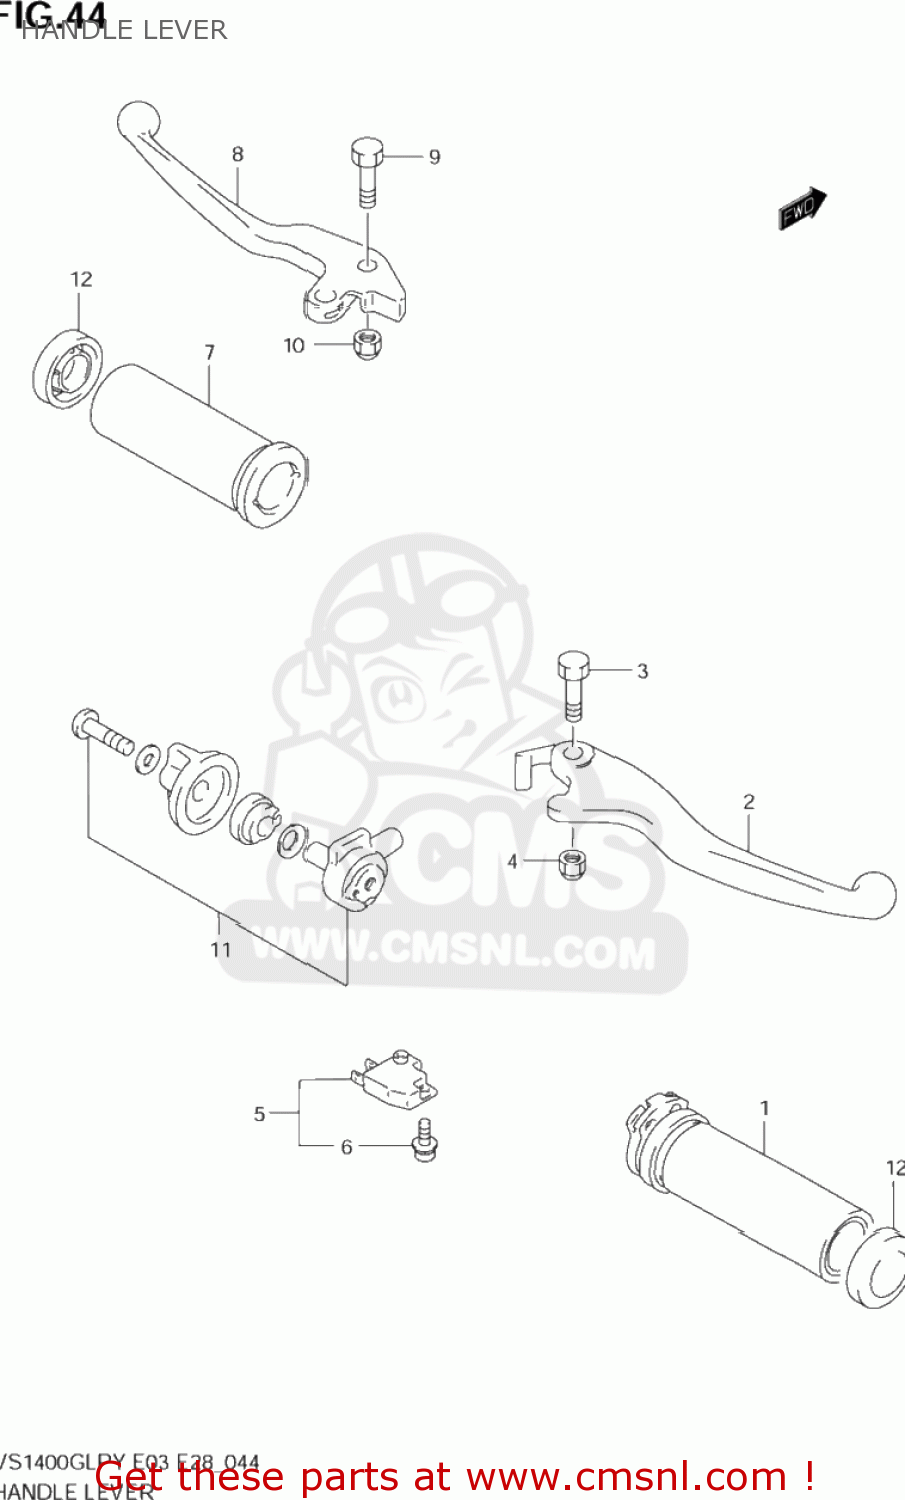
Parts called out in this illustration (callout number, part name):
1	GRIP,THROTTLE
2	LEVER,BRAKE
3	BOLT,LEVER SET
4	NUT 6MM
5	SWITCH ASSEMBLY,STOP
6	SCREW
7	GRIP,L
8	LEVER,CLUTCH
9	BOLT,LEVER SET
10	NUT 6MM
11	LEVER ASSY,STARTER
12	CAP,GRIP END
